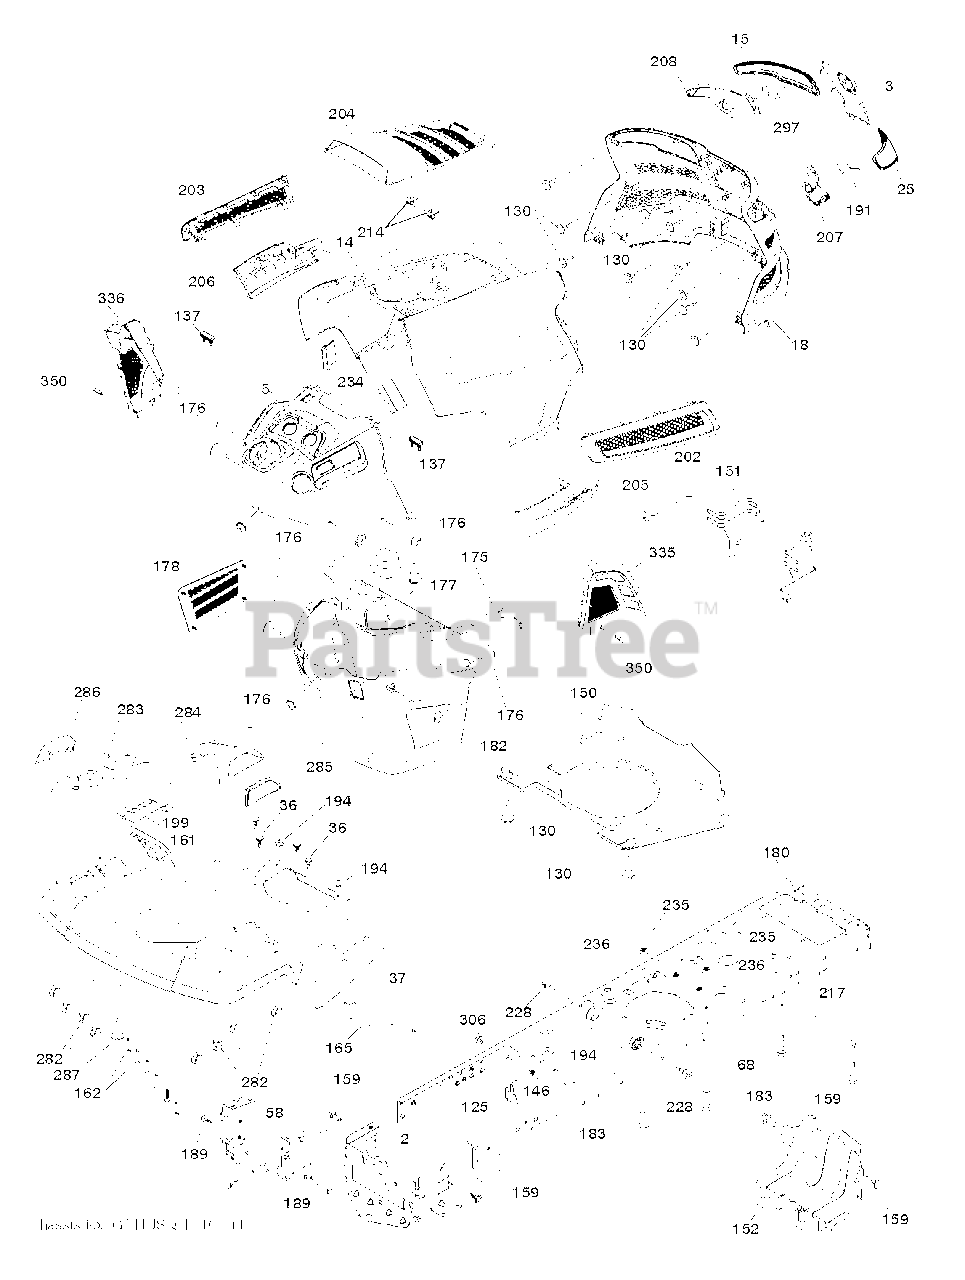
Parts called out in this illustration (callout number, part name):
2	DRAWBAR.LOWER.2PC.18/22
3	APPLIQUE.SUBASM.GT.HUSQ.II
5	DASH.UPP.GT2.DUAL.RD.PTO.MCHOK
14	HOOD.ASM.HUSQVARNA.GT.TEX.422
15	LENS.HEADLIGHT.LH.GTII.2011
18	GRILLE.SUBSTRATE.2011.
25	LENS.HEADLIGHT.RH.GTII.2011
36	SCREW 5/16"
37	FENDER.TLT.FS.W/CPH/FW/RSF.668
58	DRAWBAR UPPER 2PC SMALL FENDER
68	SCREW LT
125	CLIP.FUEL.LINE
130	SCREW.#10 X 0.750.BOS
137	BUMPER DASH
146	BOLT.RDHD.SHT.SQNK.3/8-16X5/8
150	AIR.DUCT.GTV.BLACK
151	BRACKET.PIVOT.HOOD.GT.HUSQ.II
152	SHIELD.BROWNING.PNT.GT.V2
159	SCREW, 3/8-16X3/4
161	WINDOW.FUEL.LT.HUSQ.TEX.498
162	SCREW.HI-LO.CONSOLE
165	SUPPORT.TANK.REAR.B/TE
175	PLATE.CROSSMEMBER.HUSQ
176	SCREW.#10-24X5/8.RN.QU
177	BUSHING, STEERING
178	CARGO.ASM.NET.TXGT.W/C
180	CHASSIS.TEX.BOLTED
182	DASH.LOWER.COMMON.12V.ADAPTOR
183	BOLT.5/16-18X1-1/4 FULL THD
189	SCREW
191	INSERT.REFLECTIVE.RH.HUSQ.GTII
194	NUT LOCK HEX FLANGE 5/16-18
199	PLATE.DECK.LIFT.HUSQ.LT
202	VENT.SIDE.RH.GT.HUSQ.II.
203	VENT.SIDE.LH.GT.HUSQ.II.498
204	VENT.TOP.HUSQ.GT2
205	SIDE.TRIM.RH.GT.HUSQ.II
206	SIDE.TRIM.LH.GT.HUSQ.II.GRAY
207	BEZEL LIGHT.RH.GT.II.MYLAR
208	BEZEL LIGHT.LH.GT.II.MYLAR
214	CLIP.RETAINER.TINNER.
217	ROD.PIVOT.HOOD
228	STUD.FASTNER.W/ANTI-ROTATE
234	BUMPER.HOOD.TEX.HUSQVARNA
235	SPACER FENDER
236	NUT.CENTERLOCK.5/16-
282	CLIP.RETAINER.CONSOLE.LT.HUSQ
283	CONCOLE.CNTRL.PDL.HUSQ.LT.498
284	CONSOLE.DECK.LIFT.R.SDFL.HUSQ
285	CONSOLE INSERT RH
286	CONSOLE.INSRT.LH.HUSQ.LT.BLACK
287	SCREW 1/4X20
297	INSERT.REFLECTIVE.LH.HUSQ.GTII
306	NUT LOCK FLG 3/8-16 UNC
335	COVER.LOWER.DASH.RH.BLACK
336	COVER-LH.LOWER.DASH.GT2.BLACK
350	CLIP.X-MAS.TREE
